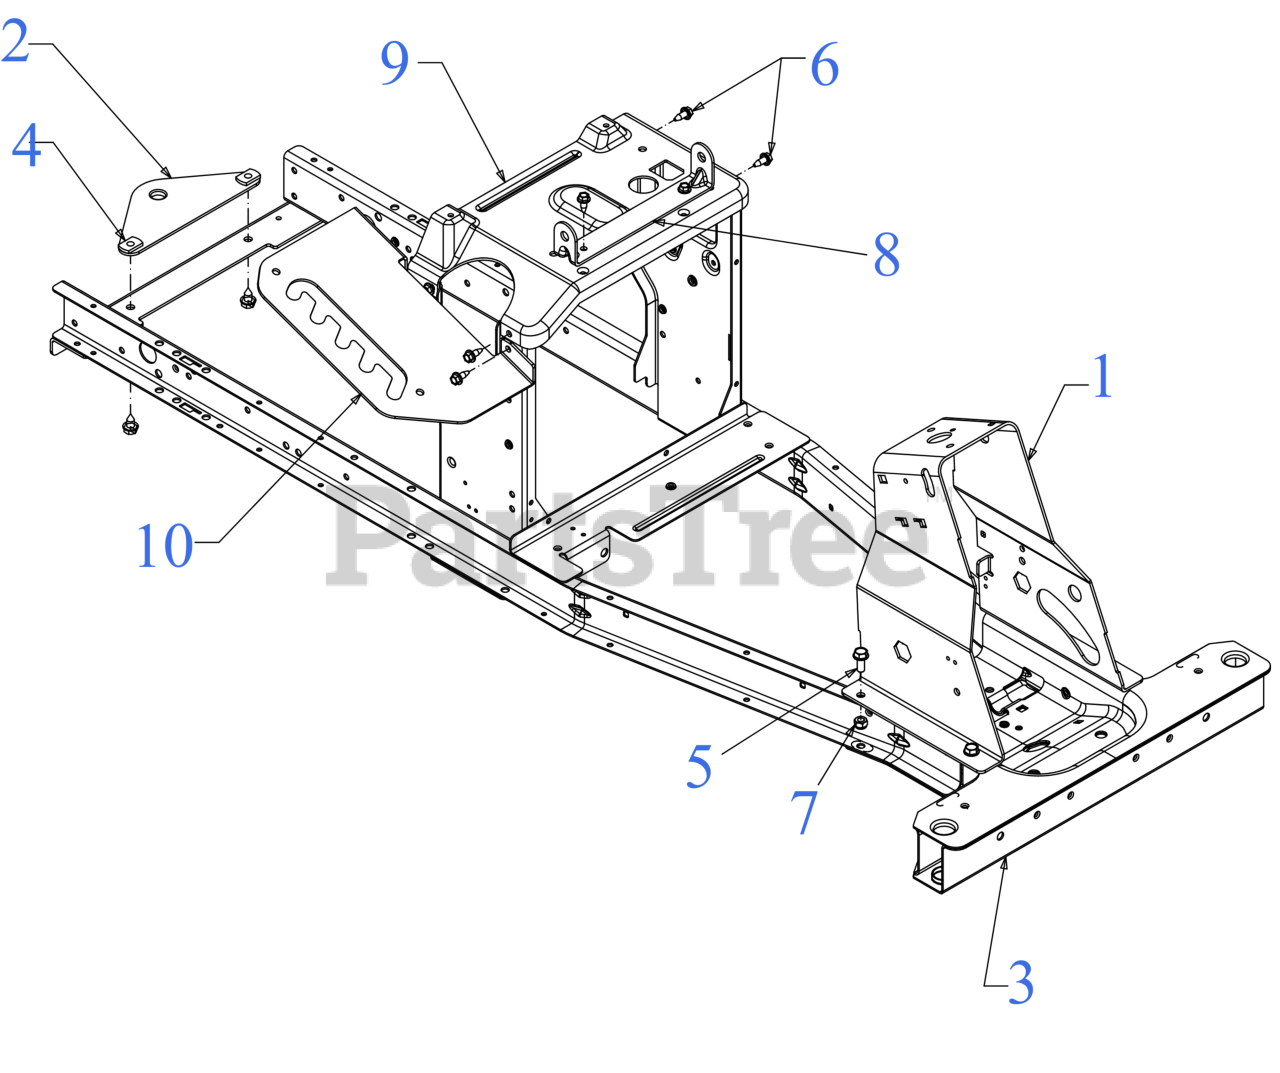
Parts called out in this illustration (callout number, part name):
1	STEERING PEDESTAL
4	SCREW 5/16-18 x .625
5	SCREW 5/16-18 x .750 GR8
6	SCREW 1/4-20X.625
8	PIVOT SEAT BRACKET
9	SEAT PAN
